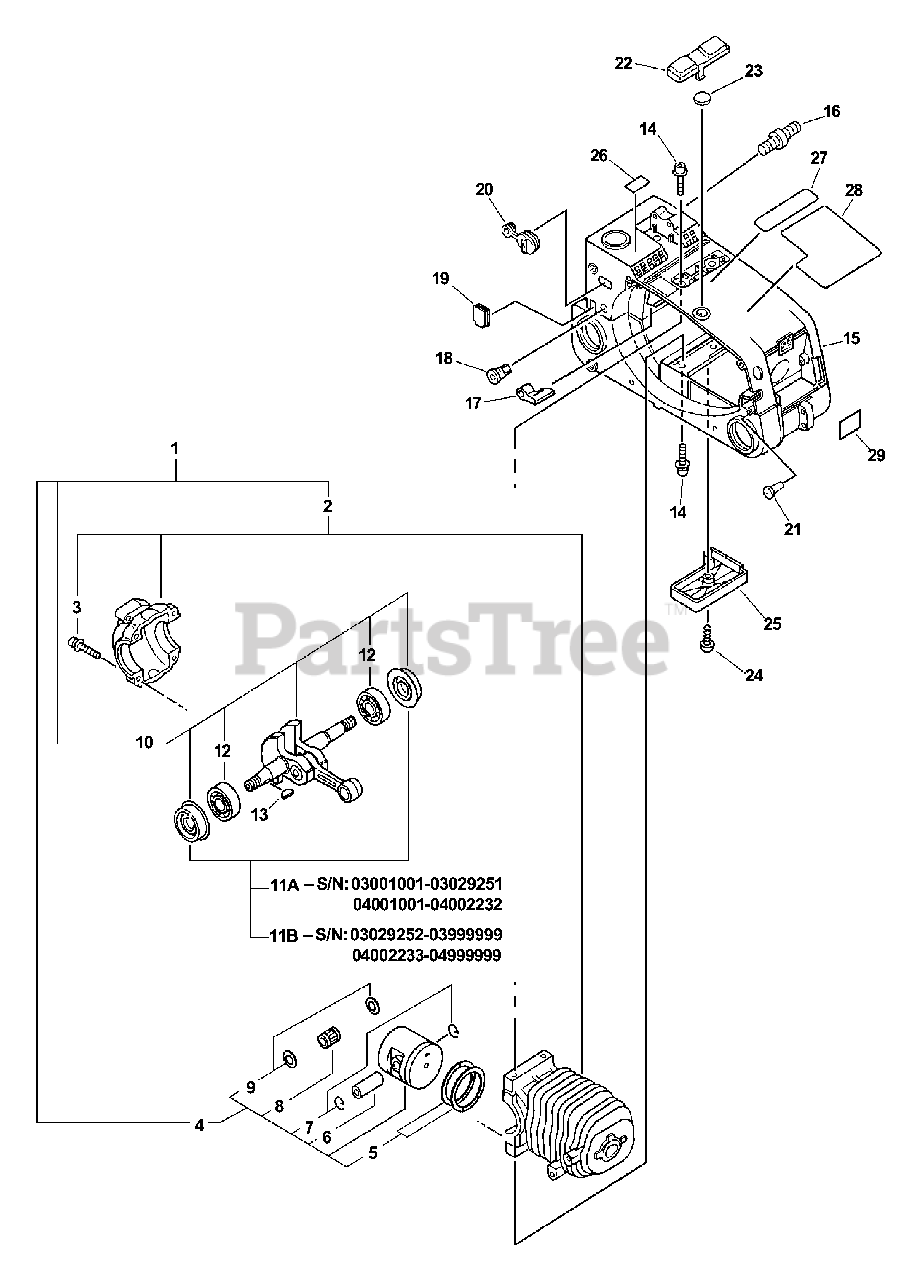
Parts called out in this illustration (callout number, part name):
1	SHORT BLOCK -- SB1069
2	CRANKCASE SET
3	SCREW - 5X25
4	PISTON KIT
5	RING, PISTON
6	PIN, PISTON
7	RING, RETAINING
8	BEARING, NEEDLE
9	SPACER, PISTON
10	CRANKSHAFT ASSY
11A	SEAL, OIL
11B	SEAL, OIL - 12
12	BEARING, BALL - 6201
14	SCREW - 5X16
15	COVER, ENGINE - GRAY
16	STUD, GUIDE BAR
21	VENT, TANK
22	COVER - GRAY
24	SCREW - 4X16
25	COVER, BOTTOM - GRAY
26	LABEL - PURGE PUMP
27	LABEL - CAUTION -- SPANISH
28	LABEL - MODEL CS-340
29	LABEL - HOT SURFACE
